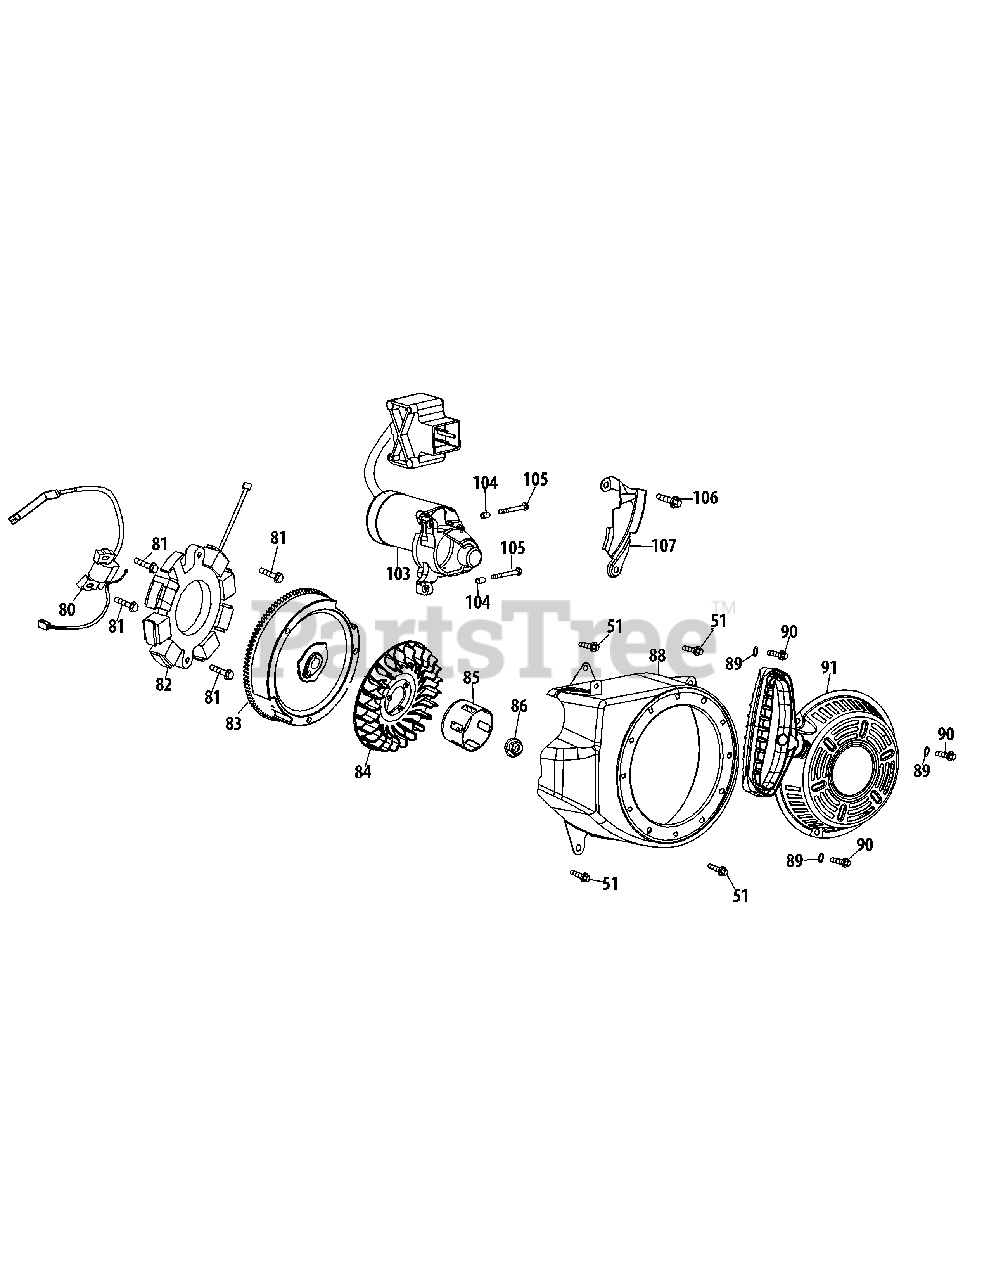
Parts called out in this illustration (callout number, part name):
51	Bolt M6×12
80	Ignition Coil Assembly
81	Bolt M6×25
82	Coil Assy/Stator
84	Fan, Cooling
85	Pulley, Starter
86	Nut, Special, M14×1.5
88	Blower Housing
89	Gasket 6 Washer
90	Bolt M6×10
91	Recoil Starter
91	Recoil Starter Handle
103	Electric Starter
104	Dowel Pin 8×8
105	Bolt M6×32
106	Bolt M6×18
107	Blower Housing Shield
